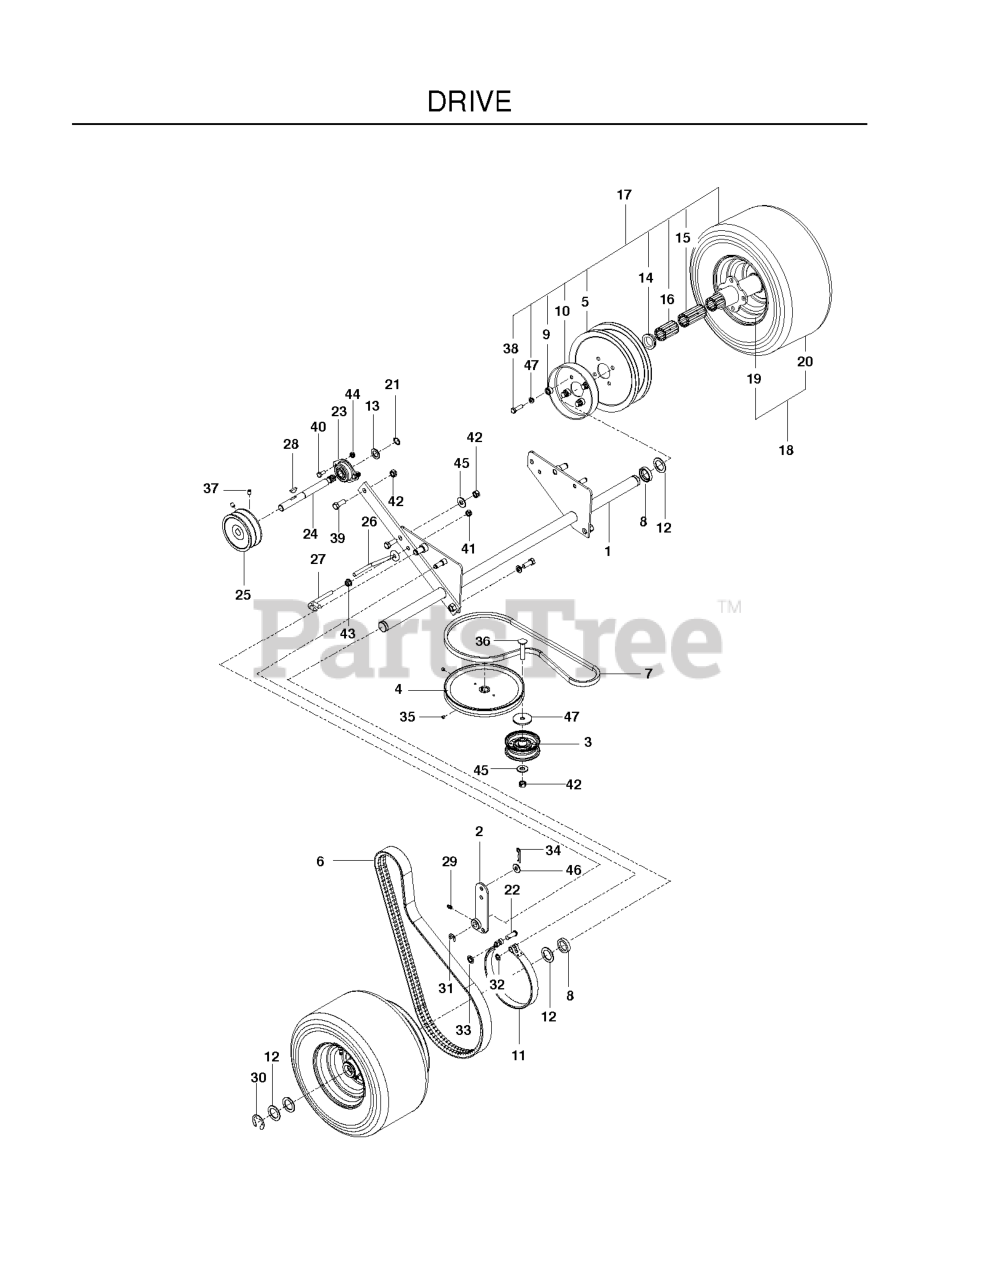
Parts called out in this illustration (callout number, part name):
1	AXLE WELDMENT (36 & 48)
2	BRAKE ARM, RIGHT
3	IDLER PULLEY
4	PULLEY, INPUT
5	TRACTION PULLEY
6	BELT, DRIVE 36/48
7	BELT, TRANSMISSION
10	BRAKE DRUM
11	BRAKE BAND
12	MACHINE BUSHING
14	BEARING FLANGE
15	ROLLER BEARING (LONG)
16	ROLLER BEARING (SHORT)
17	WHEEL PARTS KIT
18	WHEEL.ASM.13X6.5-6.SILVER.COMM
19	RIM
20	TIRE
21	RETAINER RING
22	CLEVIS PIN
24	DRIVE SHAFT
25	PULLEY, DRIVE (36 & 48)
26	BELT GUIDE
27	SCRAPER (36 & 48)
28	KEY, #9 WOODRUFF
29	ZERK
30	E-RING 1"
31	E-RING 1/2 (2 2)
32	E RING 3/8"
33	NUT 3/8 PALNUT RTNG BLK PHOS
34	HAIRPIN #2
35	SETSCREW, 1/4-20 NYLOC
36	RHSNB 3/8C X 2
37	SET SCREW 5/16 NYLOC
38	HCS 3/8C X 1 1/2
39	HCS 3/8-16X1.GRD.5.ZD
40	HCS 1/4C X 5/8
41	NUT 5/16C CENTERLOCK
42	NUT 3/8C CENTERBLOCK
43	NUT 5/16C WHIZ
44	NUT 1/4C CENTER LOCK
45	WASHER 3/8 FLAT
46	WASHER 5/16 FLAT
47	SLW 3/8 STD
